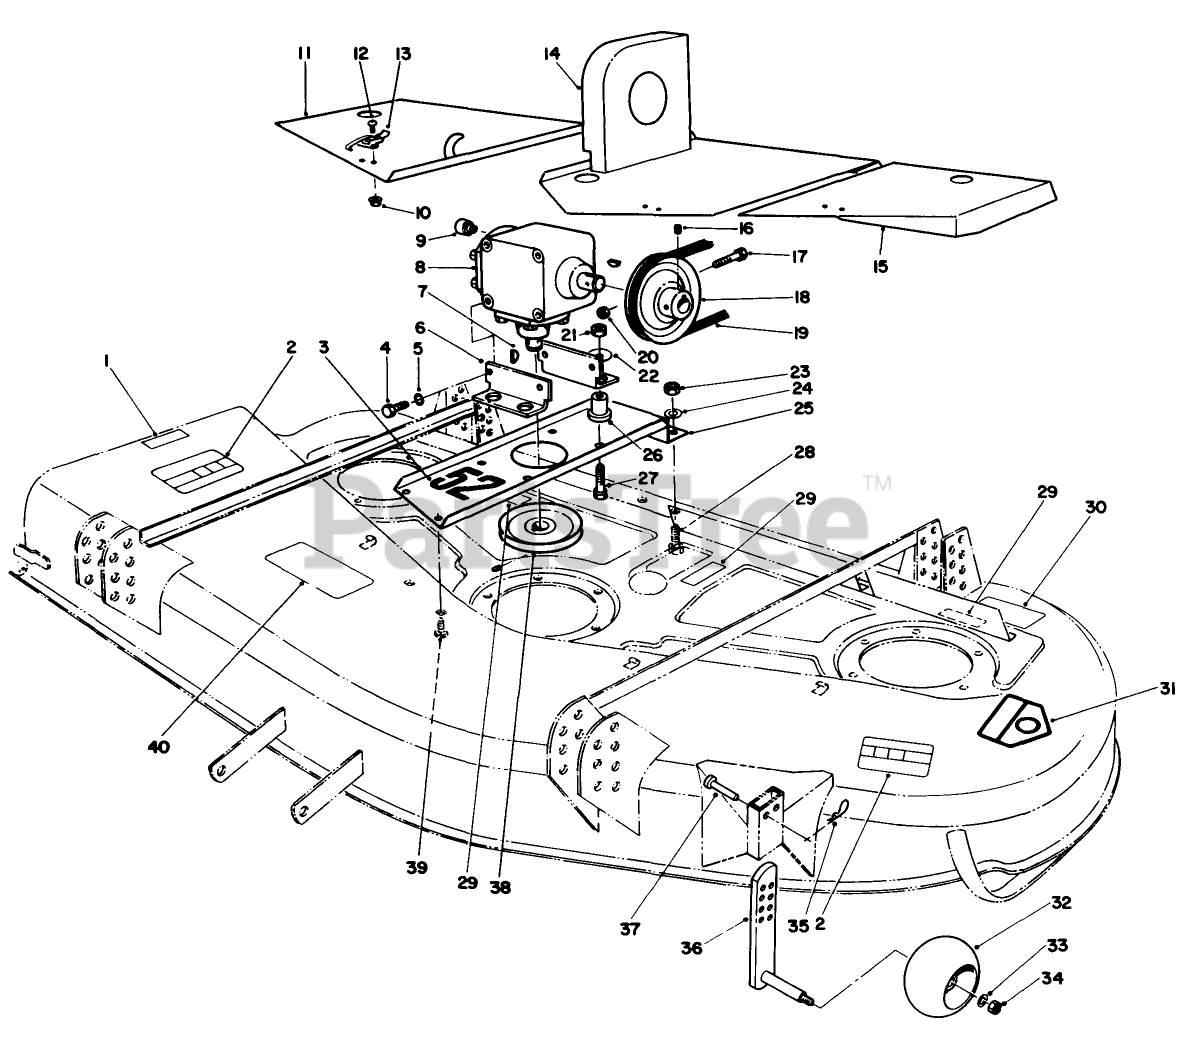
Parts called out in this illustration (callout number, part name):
1	DECAL-DANGER
2	DECAL-DANGER, THROWN OBJECT
3	DECAL
4	SCREW-HH
5	WASHER-LOCK
6	Bracket Mounting
8	Gear Box
9	FITTING-LUBE
10	NUT-LOCK, FLANGE
11	Bolt
12	SCREW-HWH
13	CLAMP-SLOTTED
14	Center-Cover
15	Cover-Deck
16	SCREW-SET, SQH
17	SCREW-HH
18	PULLEY
19	V-BELT, DECK
20	NUT-LOCK, NI
21	NUT-LOCK, SIDE
22	WASHER
23	NUT-LOCK, NI
24	WASHER-FLAT
25	Base-Gear Box Mount
26	MOUNT
27	SCREW-HH
28	SCREW-HH
29	DECAL-DANGER
30	DECAL-TORQUE
31	DECAL-DANGER
32	WHEEL-GAGE
33	WASHER-FLAT
34	NUT-LOCK, NI
35	PIN-HAIR
36	GAGE-WHEEL
37	PIN-CLEVIS
38	PULLEY
39	BOLT-CARR
40	DECAL-WARNING
